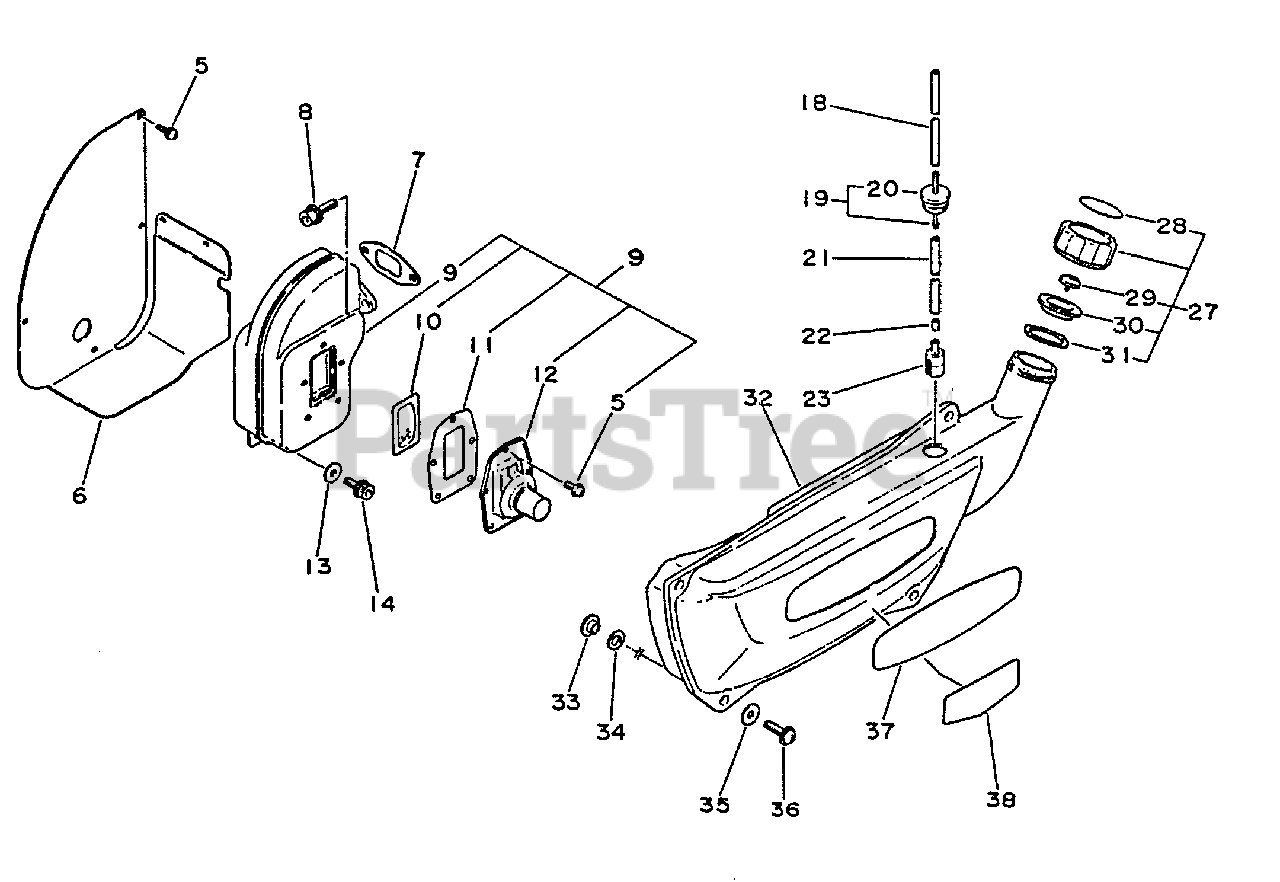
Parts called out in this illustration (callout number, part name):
5	SCREW 4×10
6	INSULATOR
7	GASKET, EXHAUST
8	BOLT 6×20
9	MUFFLER ASSY
10	SCREEN, SPARK ARRESTER
11	GASKET
12	GUIDE, EXHAUST
13	WASHER 5.2×16×1.0
14	BOLT 5×14
18	PIPE, FUEL
19	GROMMET KIT
21	PIPE, FUEL
22	VALVE, CHECK
23	FILTER, FUEL
27	CAP ASSY
28	LABEL - FUEL MIX
29	VENT ASSY
30	HOLDER, CHECK VALVE
31	GASKET, FUEL CAP
32	TANK, FUEL
35	WASHER 5.5×18×1
36	SCREW 5×20
37	LABEL - ECHO
38	LABEL, MODEL
